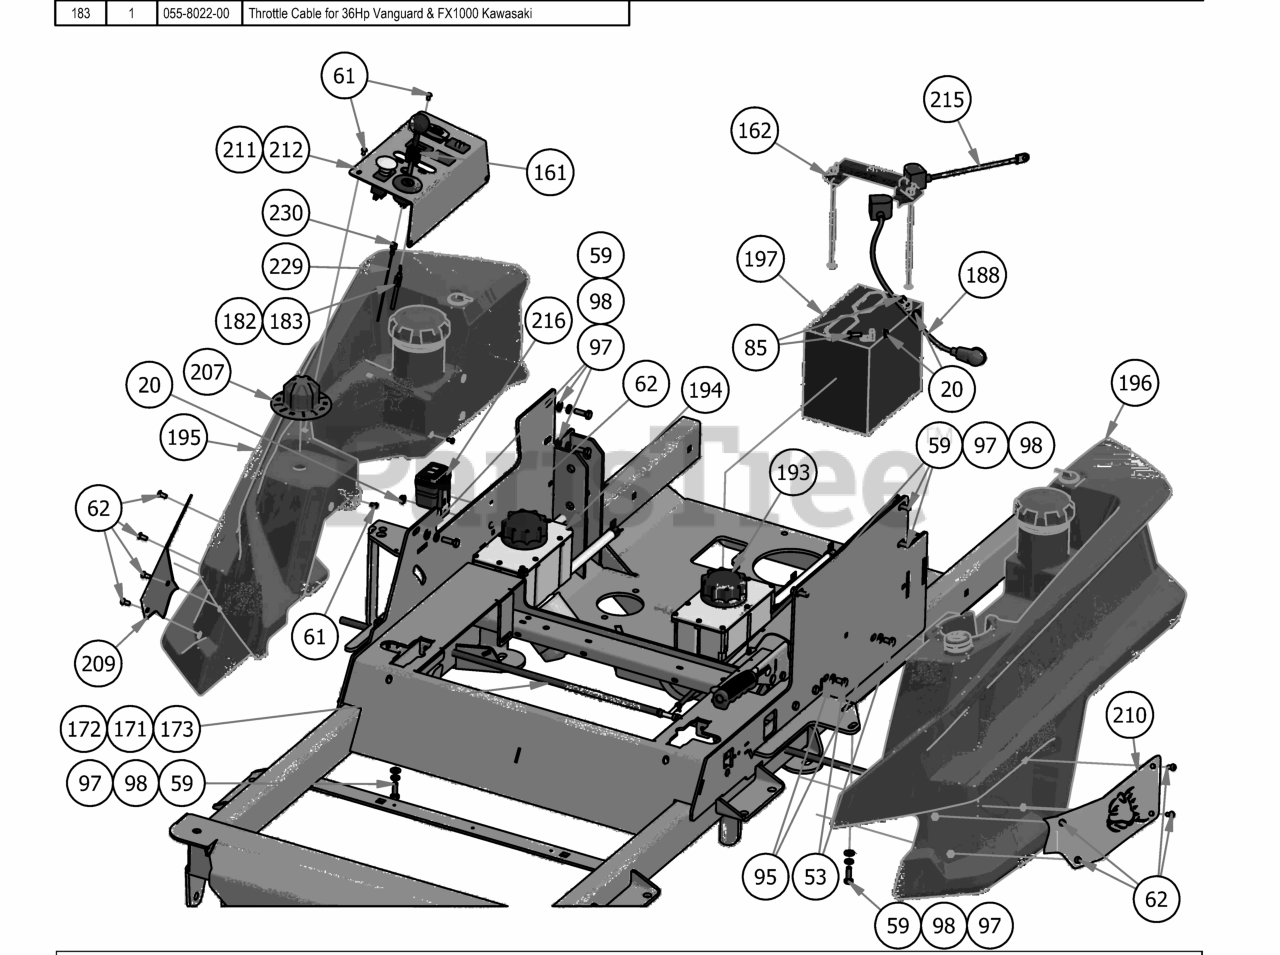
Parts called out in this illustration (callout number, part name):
20	1/4-20 Hex Flange Nuts Zinc w/Serrations
53	5/16"-18 x 1/2 GR5 Hex bolt zink
59	5/16" x 1" Bolt
61	10-32 x 3/8" Button Socket Head Bolt
62	1/4" x 1/2" BS C/S 18-8 SS
85	1/4" x 3/4" Hex Bolt
95	1/4" Flat Washer
97	5/16" Flat Washer
98	5/16" Lock Washer
161	Ignition Key
162	Hold Down Assembly
171	2019 Rebel Rogue Renegade Fuel Line for Vanguard & Yamaha
172	2019 Rebel Rogue Renegade Fuel Line for Kohler
173	2019 Rebel Rogue Renegade Fuel Line for Kawasaki
182	Outlaw Throttle Cable
183	Throttle Cable for 36Hp Vanguard & FX1000 Kawasaki
188	24" Red Battery Cable
190	Seat Cable
193	LH Rogue Hydro Tank Assy
194	RH Rogue Hydro Tank Assy
195	2019 Right Rebel, Rogue, Renagade Fuel Tank (GAS)
196	2019 Left Rebel, Rogue, Renegade Fuel Tank (GAS)
197	Battery
204	2019 Veritical Suspension Frame
207	2019 Deck Height Dial
209	2019 Outlaw Fuel Tank Insert - Right
210	2019 Outlaw Fuel Tank Insert - Left
211	Rebel/Rogue EFI Control Panel Assy
212	Rebel/Rogue Control Panel Assy
215	Starter Cable
216	2019 Wiring Harness-Rebel/Rogue
229	16 AWG Black Insulated Wire for Tachometer
230	1/4" Female Quick Connect Terminal
